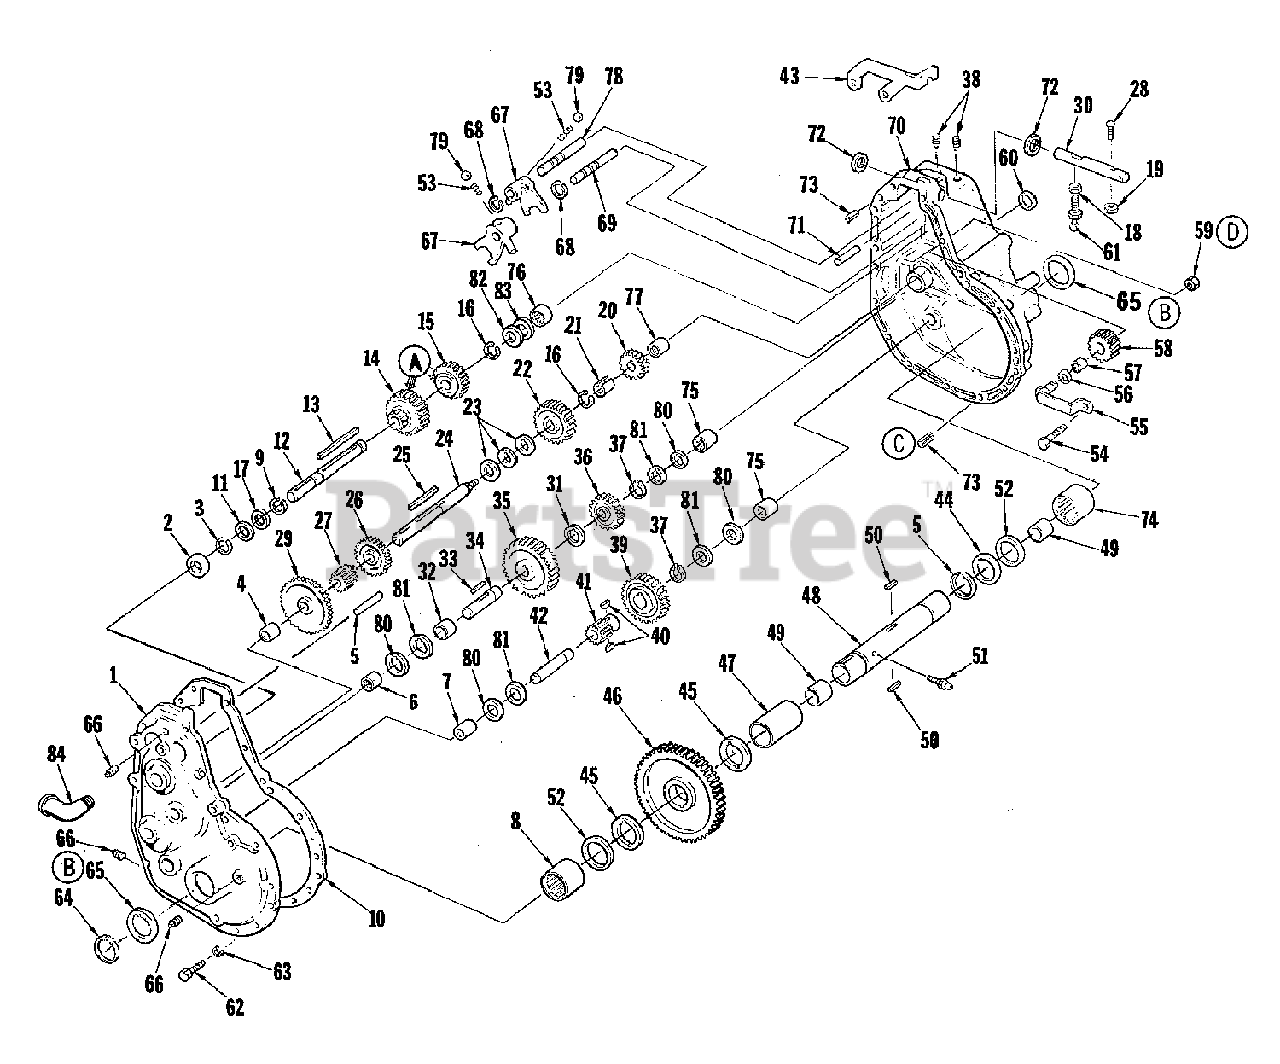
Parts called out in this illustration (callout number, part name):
1	COVER, Gear Case Sub Assembly
3	RING, Retaining
4	BEARING, Needle
5	ROLL PIN ASSEMBLY
6	BEARING, Needle
7	BEARING, Needle
8	BEARING, Needle
9	RING, Retaining
10	GASKET, Gear Case
12	SHAFT, Pulley
14	PINION ASSEMBLY
15	PINION ASSEMBLY, Rev. & II
16	RING, Retaining
18	NUT, Full, 3/8-24
19	NUT, Hex Jam Fin, 5/16-18
20	PINION, Rev. & IV
22	GEAR, Driven II
23	SPACER, Transmission Gear
24	SHAFT, 1st Intermediate
26	PINION, Driven III
27	PINION, 1st Intermediate
28	BOLT, Round Head, 5/16-18 x 1
29	GEAR, Driven 1st
30	ROD, Shift Assembly
34	SHAFT, 2nd Intermediate
35	GEAR, 2nd Intermediate
36	PINION, 2nd Intermediate
37	RING, Retaining
38	SCREW, Set Socket head, 5/16-18 x 1/2
39	GEAR, 3rd Intermediate
40	KEY, Woodruff #6
41	PINION, 3rd Intermediate
42	SHAFT, 3rd Intermediate
43	SUPPORT, Switch
45	WASHER, Axle Tube
47	SPACER, Axle Tube
48	TUBE & BUSHING ASSEMBLY
51	FITTING, Lube
54	SCREW, Hex Head Cap, 3/8-16 x 1-1/4
55	PIN ASSEMBLY, Reverse Gear
57	SPACER, Reverse Gear
58	GEAR, Reverse
59	NUT, Hex Lock Fin
62	SCREW, Hex Head Cap, 5/16-18 x 1
63	WASHER, Lock, 5/16
68	RING, Retaining
69	SHAFT, Shifter, Hi-Lo
70	CASE, Gear Sub Assembly
71	ROLL PIN SUB ASSEMBLY
74	BEARING, Needle
75	BEARING, Needle
76	BEARING, Needle
77	BEARING, Needle
78	SHAFT, Shifter Reverse Medium
79	BALL, Shift Lock
84	ELBOW, Street
